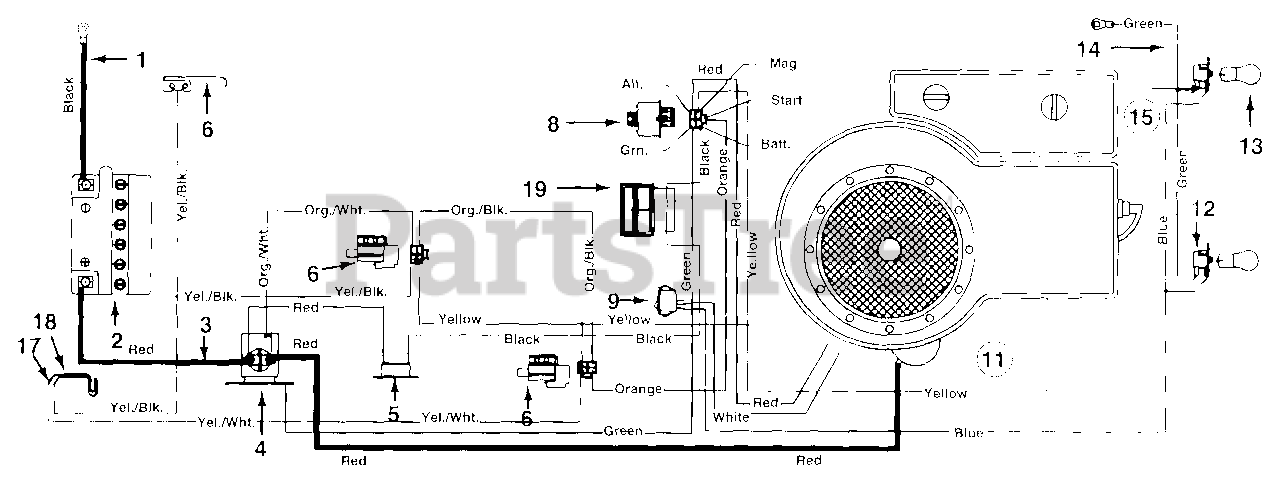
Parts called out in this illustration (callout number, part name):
1	Ground Wire
2	Battery
3	Electric Wire - 8.0" Lg.
4	Solenoid
5	Circuit Breaker
6	Spring Switch (Reverse)
8	Ignition Switch
9	Light Switch
11	Harness w/Amp & Light Switch
12	Socket (Sq. Headlights) - Style 0, 1
13	Bulb (Sq. Headlights)
14	Ground Wire
15	Headlight Harness w/Amp & Light Switch
17	Safety Switch (Seat)
18	Safety Switch (Seat)
19	Ammeter
